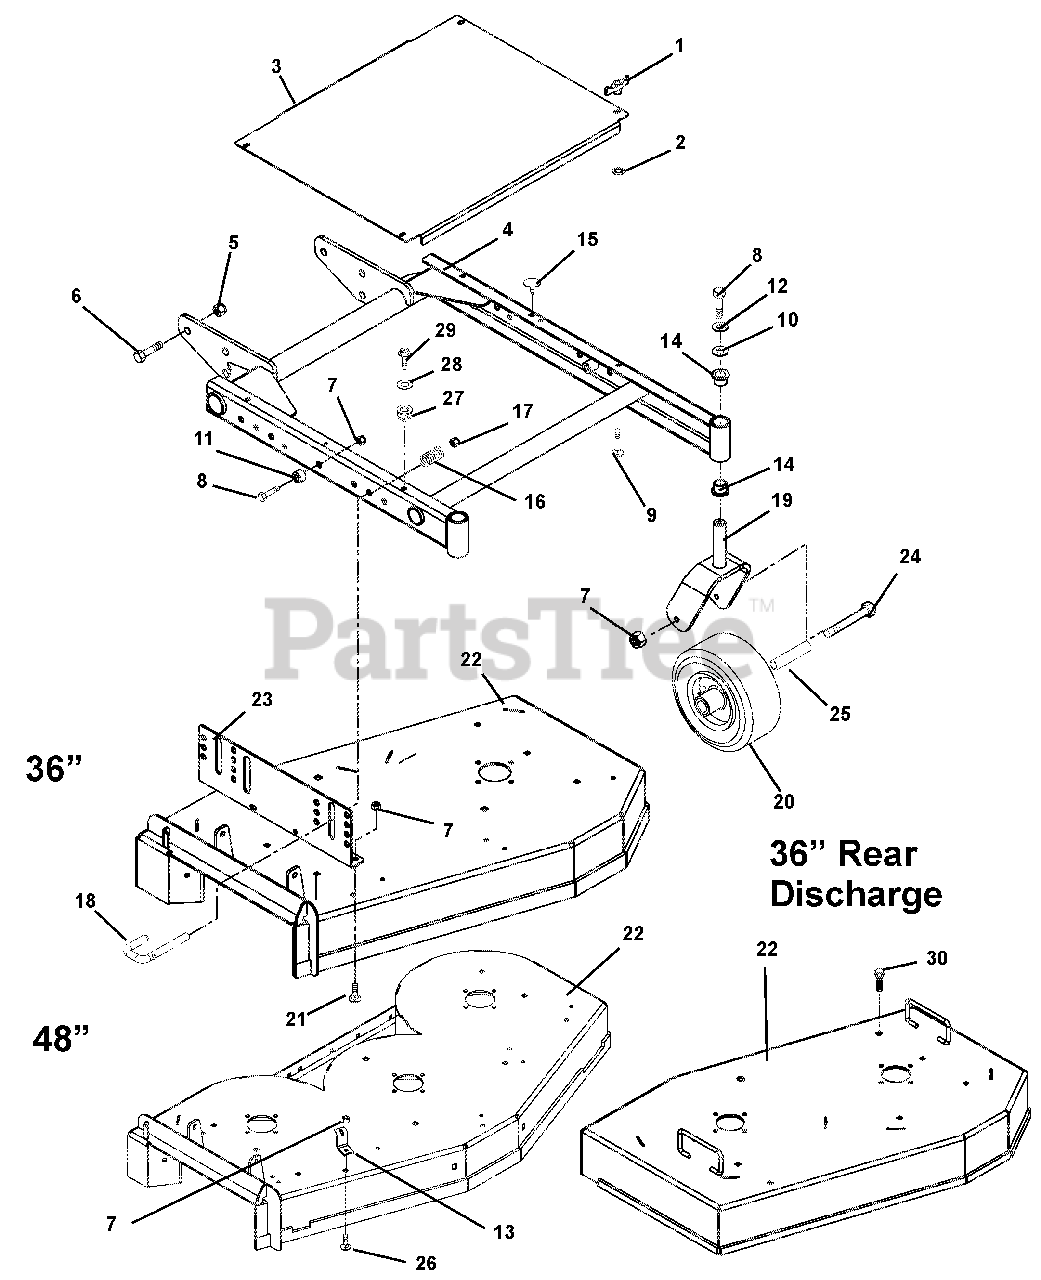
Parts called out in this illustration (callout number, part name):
1	Knob- Wing .312-18 (106, 120)
2	Nut-Push .312 (106, 120)
3	Cover, Belt Pro Mower (120, 314)
4	Weldment - Mower Frame 36" (120, 314)
5	Nut-Locking-Nylon .625-11
6	Bolt-Hex .62-11 x 1.50
7	Nut-Locking-Top-Flange .38-16 (120)
8	Bolt-Hex .38-16 x 1.25 Grade 5
9	Bolt-Round Head Square Neck .31-18 x 1.00 (106, 120)
10	Washer-Flat-Steel .38 x 1.50 x .125
11	Bushing
12	Washer-Locking .38 x .094 Regular
13	Anchor, Spring (106)
14	Bushing-Flange 1.00 x 1.25 x 1.50 x 1.50
15	Bumper Grommet .125 x .25 Dia.
16	Spring-Compression .058 x .65 x 2.13
17	Nut-Locking-Center .50-13
18	Pin- Latch
19	Weldment-Caster Fork
20	Wheel 9 x 3.50
21	Bolt-Round Head Square Neck .38-16 x 1.00 Grade 5 (106, 120)
22	Kit, 36" Fixed Mower Deck with Decals (120)
23	Kit-Mower Side Support Bracket-Right Hand and Left Hand (314)
24	Bolt-Hex .38-16 x 5.50
25	Bearing .625 x .380 x 4.08
26	Bolt-Round Head Square Neck .38-16 x .75 Grade 5
27	Grommet, Plastic (314)
28	Washer-Flat-Steel .281 x .62 x .065 (314)
29	Screw-Tapping .25-20 x .50 Hex Washer Head (314)
30	Bolt-Hex .38-16X1.00 Grade 5 (314)
